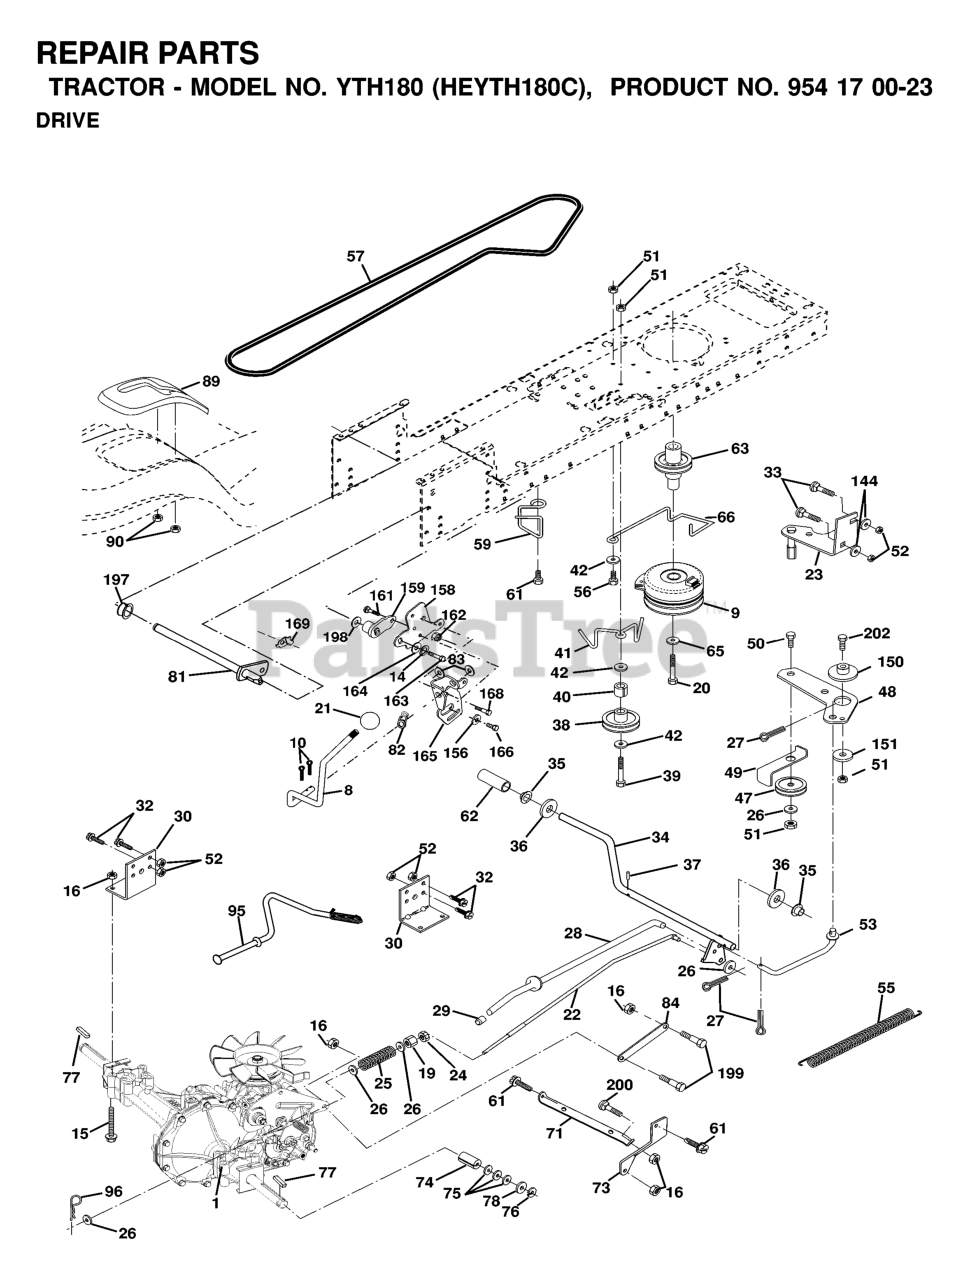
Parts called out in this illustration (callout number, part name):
8	ROD SHIFT FENDER ADJUST STLT
9	ELECTRIC CLUTCH
10	PIN COTTER
14	LOCKWASHER
15	BOLT HEX 5/16-18 GR 5
16	NUT.71038.31-18.HEX.NYLOCK
19	NUT
20	BOLT HEX
21	KNOB.DUCKHEAD.1/2
22	ROD BRAKE HYDRO
24	NUT
25	SPRING ROD LT
26	WASHER
27	COTTER PIN
28	ROD BRAKE PARK LT
29	PLUNGER CAP
30	BRKT, TRNSXLE MNT 20"
32	BOLT
33	RP BOLT 5/16-18 X3/4 ZN/YEL GR
34	SHAFT, FOOT PEDAL
35	BEARING.NYLON
37	DRIVE PIN
38	FLAT IDLER PULLEY
41	KEEPER.BELT.IDLER.FLAT
42	WASHER
47	IDLER PULLEY
48	BELLCRANK, CLUTCH
49	RETAIN BELT
50	BOLT
52	LOCKNUT
53	LINK, CLUTCH LT
55	SPRING, RETURN LT
57	BELT
59	Keeper, Center Span
61	SCREW 3/8-16X3/4
62	COVER, PEDAL (1 2)
63	PULLEY, CLUTCH ELECT EVX
65	LOCKWASHER
66	KEEPER BELT ENGINE
71	STRAP TORQUE LH HYDRO
73	STRAP TORQUE RH HYDRO
74	SPACER AXLE
77	SQUARE KEY
81	SHAFT ASM CROSS TAPERED
82	SHIFT SPRING
83	WASHER
84	LINK TRANSAXLE
89	SHIFT CONSOLE
90	NUT.PUSH.3/16
95	CONTROL ASM. BYPASS HYDRO
96	RETAINER M
144	Washer 11/32 x 5/8 x 16 Ga SD
150	BUSHING.BELLCRANK.GRD.DR
151	WASHER 12/32X2X10GA
156	WASHER.SRRTD.5/16
158	BRACKET
159	HUB
161	BOLT
162	NUT.CROWNLOCK.1/4
164	Washer 5/8 x .281 x 10 Ga.
165	RP BRACKET
168	BOLT.SHOULDER.5/16-18X
169	PLATE.FASTENING.CROSS.SHAFT
197	NYLINER SNAP 5/8" ID
198	WASHER.NYL.7/8IDX.105"HYD CR
199	BOLT SHOULDER 5/16-18 UNC
200	Bolt Rdhd Sq Neck 5/16-18 x 1 Unc
202	BOLT.3/8-16X1.50
